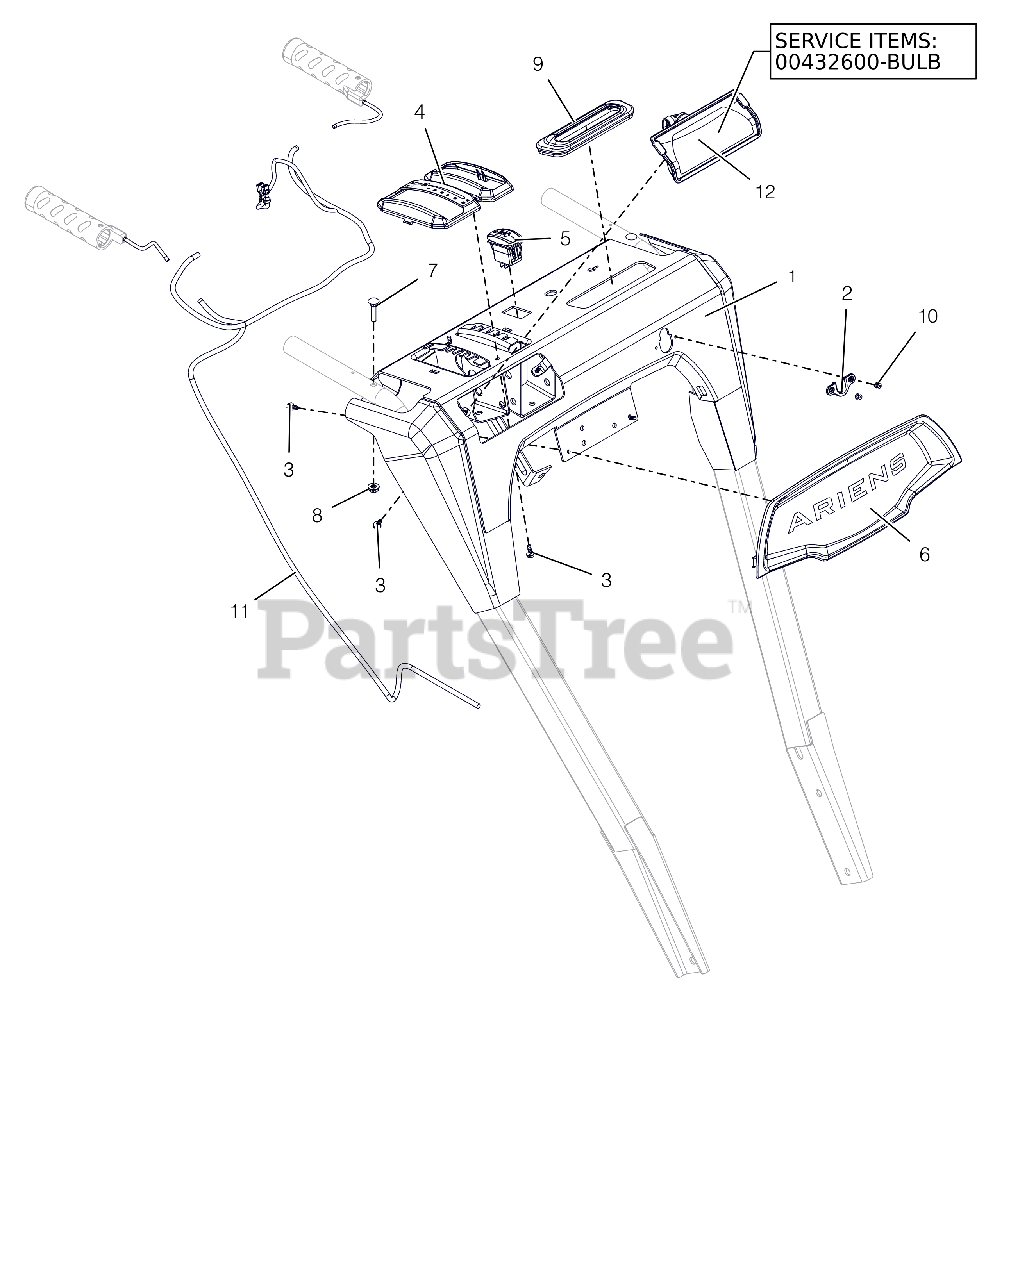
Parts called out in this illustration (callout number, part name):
1	PANEL, DASH-FRICTION W/DECAL
2	GROMMET, CABLE, QUICK TURN 2
3	SCR-TAP #10X.50 BOSS INDHXHD
4	BEZEL, SHIFT - FRICTION SNOW
5	SWITCH,ROCKER SPST-ON/OFF
6	BEZEL, DASH - ARIENS LG DASH
7	BLT-RDHDXLSQNK.25-20X1.25 G5ZC
8	@NUT-LK-CTR-FLG .25-20 YWZC
9	GROMMET, BOOT, QUICK TURN
10	RVT-POP #43 .125X.313 STL ZINC
11	HARNESS, LIGHT & WARMER
12	HEADLIGHT ASY, HALO 20W 2SHOT
12	BULB, LIGHT-HALOGEN 20W
